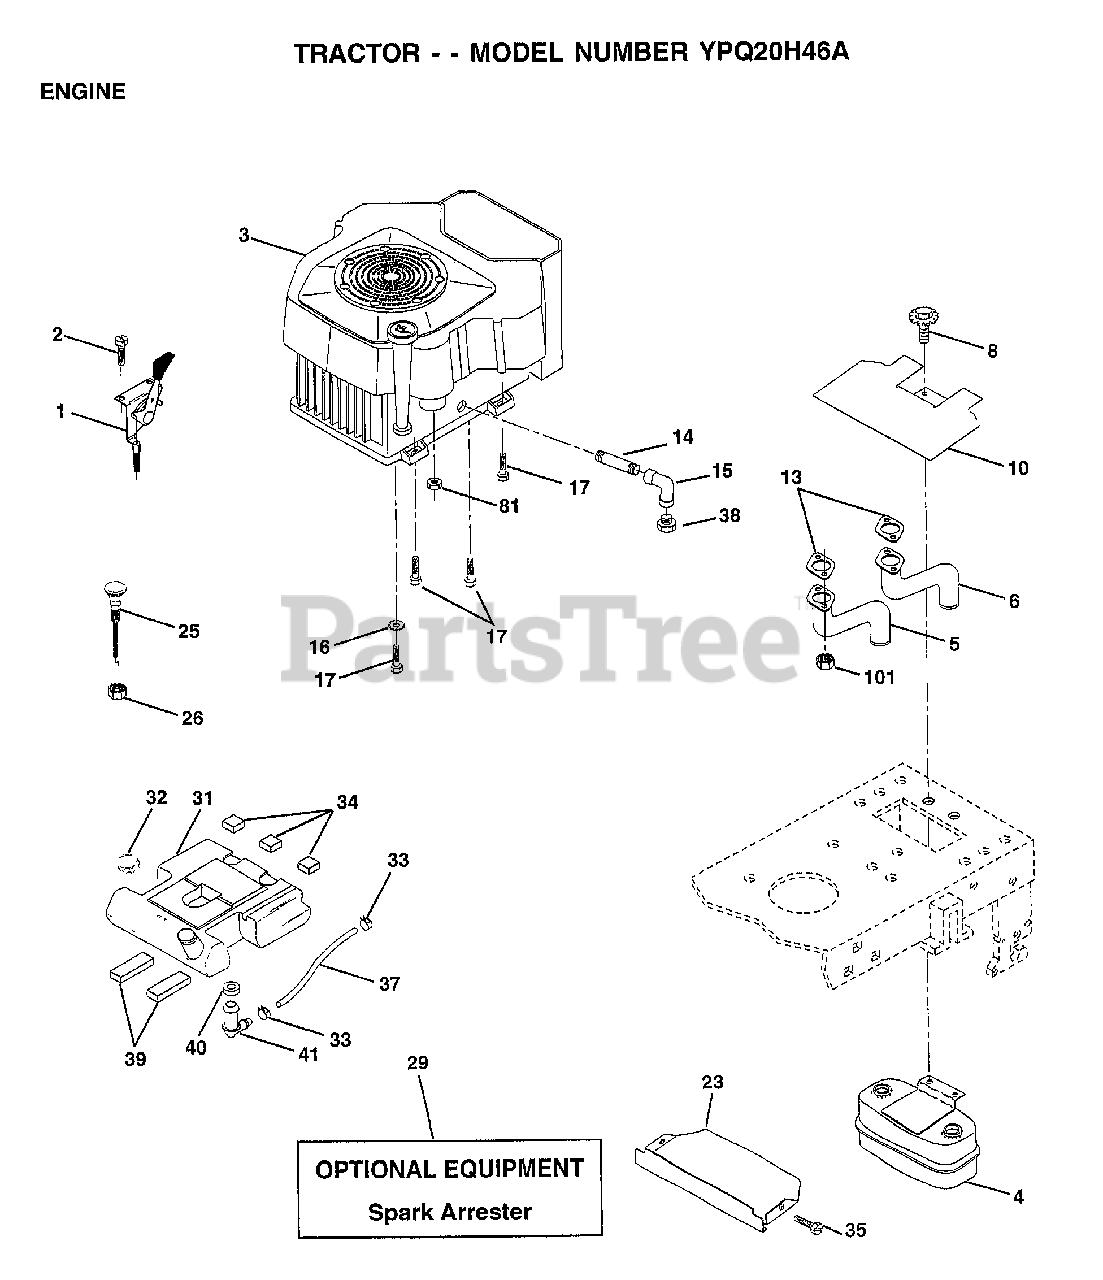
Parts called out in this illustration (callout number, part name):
2	SCREW LT
4	MUFFLER.TW.LOTONE
5	PIPE-EXHAUST.LH
6	PIPE-EXHAUST.RH.
8	BOLT.5/16-18.UNC
10	SHIELD.HEAT.MUFF.
13	GASKET
14	PIPE NIPPLE LT
15	ELBOW
16	LOCKWASHER
17	SCREW LT
23	SHIELD.BRN/DBR.GD
25	CONTROL.CHOKE.37
26	"NUT,KEPS 3/8-24IM"
31	TANK FUEL REAR
32	CAP ASM FUEL
33	HOSE CLAMP
34	PAD-SPACER LT
35	SCREW
37	FUEL LINE T
39	PAD IDLER TI
40	BUSHING OUTLET T
41	STEM.TANK.FUEL
81	NUT
101	NUT FLANGE M8-125
